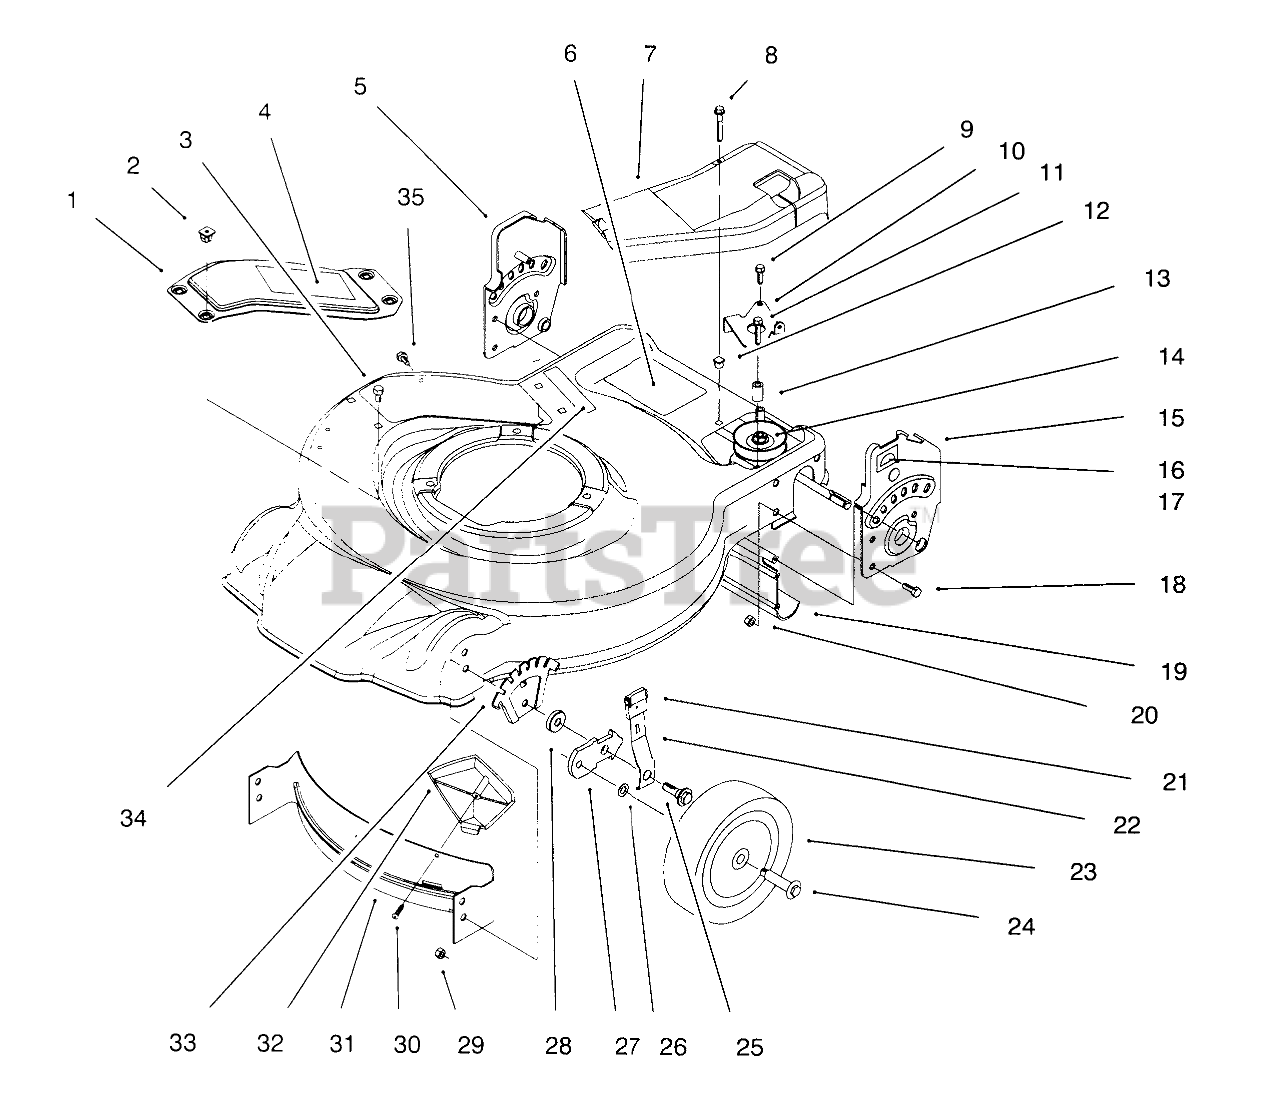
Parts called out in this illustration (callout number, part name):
1	Cover Recycling (Incl. Ref. #4) (Model No. 20442 & 20444)
2	NUT - CLIP
3	SCREW-HWH
4	DECAL - COVER
5	RH HANDLE BRACKET ASM
6	DECAL-WARNING
7	COVER-TRANSMISSION
8	SCREW-PTH
9	SCREW-HWHTF
10	Brkt-Belt Guide
11	SCREW-HWHTF
12	NUT-CLIP
13	BUSHING-PLATE, ACTUATOR
14	ASM-Transmission
15	LH HANDLE BRACKET ASM
16	DECAL-HOC, RH
17	DECAL-HOC, LH
18	SCREW-HH
19	SHIELD-TRAILING
20	NUT-LOCK, NI
21	KNOB-LEVER, HEIGHT ADJUSTMENT
22	ARM-FRONT SPRING
23	WHEEL ASM
24	BOLT-SHOULDER
25	BOLT-SHOULDER
26	WASHER
27	Bracket-H.
28	WASHER
29	NUT-LOCK, NI
30	SCREW-PPH
31	Baffle Front
32	KICKER-FRONT
33	Plate H.O.C.
34	DECAL - WARNING
